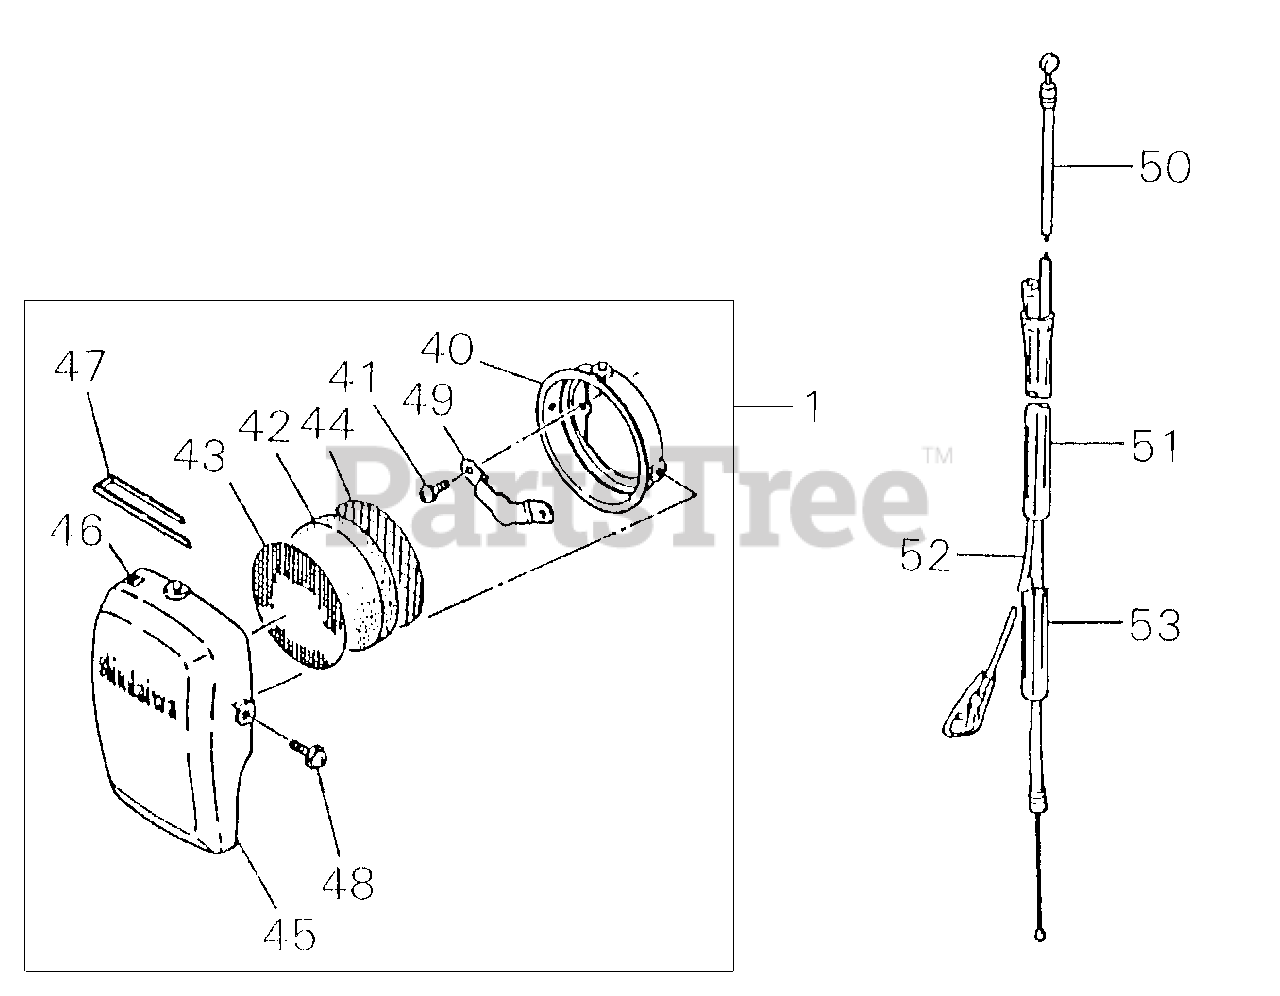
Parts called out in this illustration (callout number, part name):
1	FILTER ASSY, AIR
40	CASE, AIR FILTER
41	SCREW
42	FILTER, AIR
43	SCREEN - FRONT
44	SCREEN, REAR
45	COVER, AIR FILTER
46	LABEL, CHOKE
47	CLIP, FILTER RETAINING
48	SCREW 4
50	CABLE, THROTTLE
51	TUBE, PROTECTIVE
52	LEAD - GROUND
53	TUBE, PROTECTIVE
